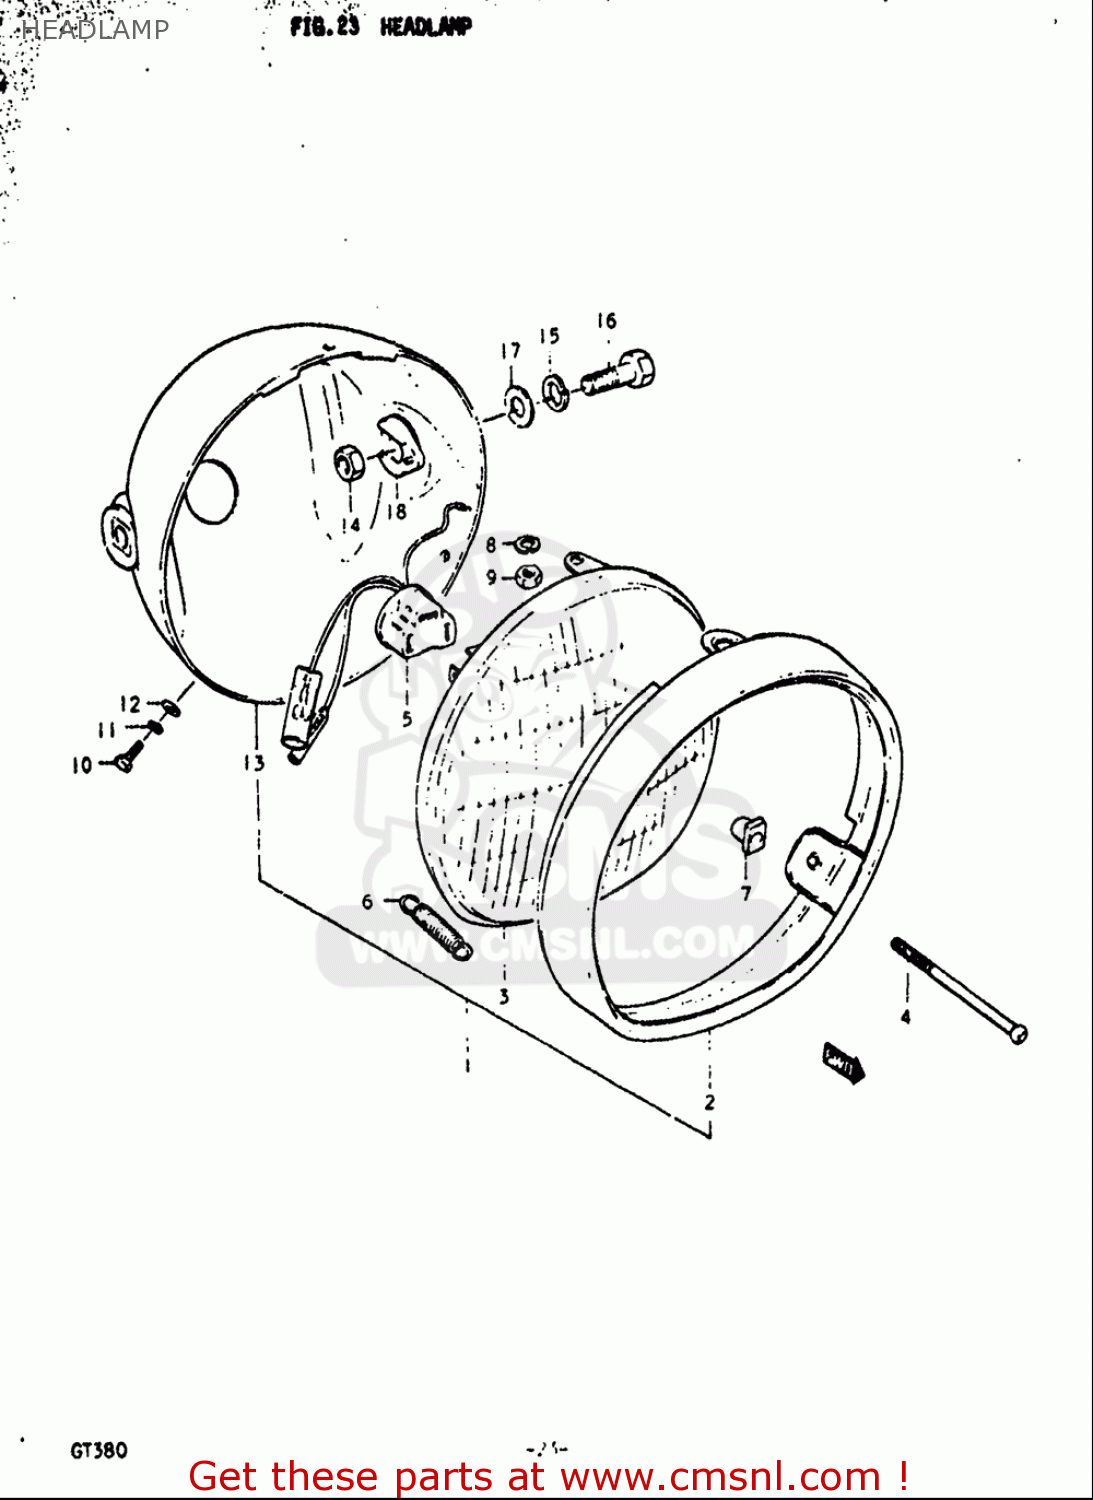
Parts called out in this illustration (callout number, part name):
6	SPRING,HEADLAMP ADJUST
7	NUT
8	WASHER,LOCK
9	NUT
10	SCREW
11	WASHER,LOCK
12	WASHER
14	NUT
15	WASHER,LOCK
17	WASHER
